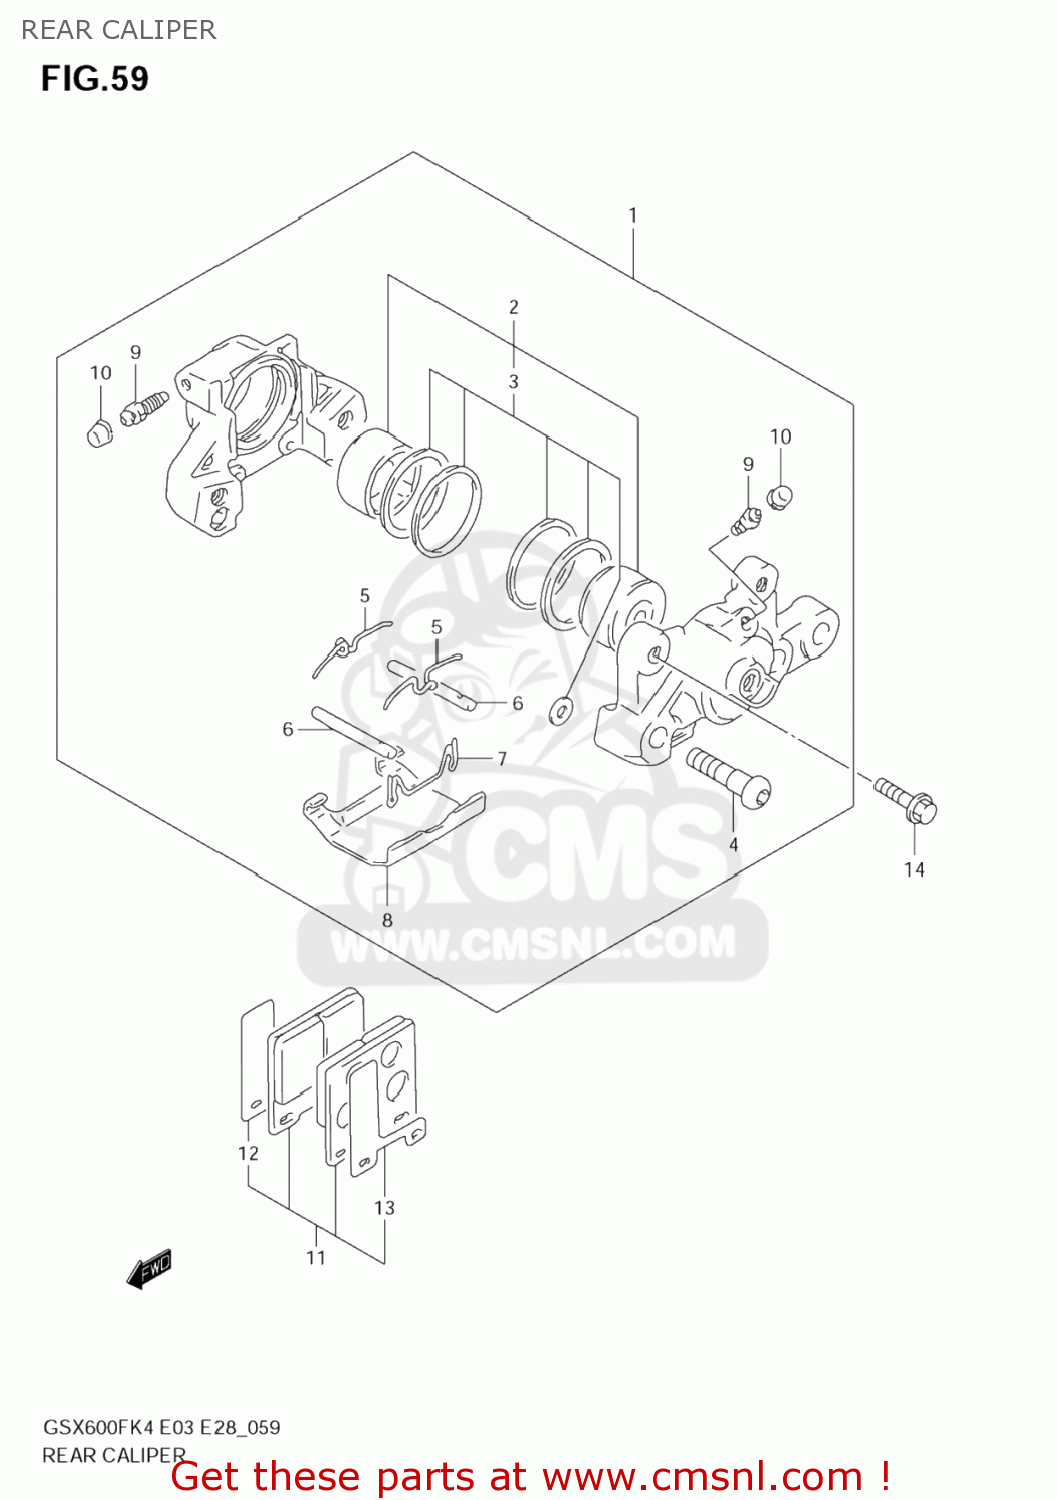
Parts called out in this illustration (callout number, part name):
1	CALIPER ASSY,RR
2	PISTON SET
3	SEAL SET,PISTO
4	BOLT,HOUSING
5	SPRING
6	PIN,PAD
7	CLIP,PAD PIN
8	COVER
9	BLEEDER
10	CAP,BLEEDER PLUG
11	PAD & SHIM SET (NAS)
12	SHIM,INNER
13	SHIM,OUTER
14	BOLT
